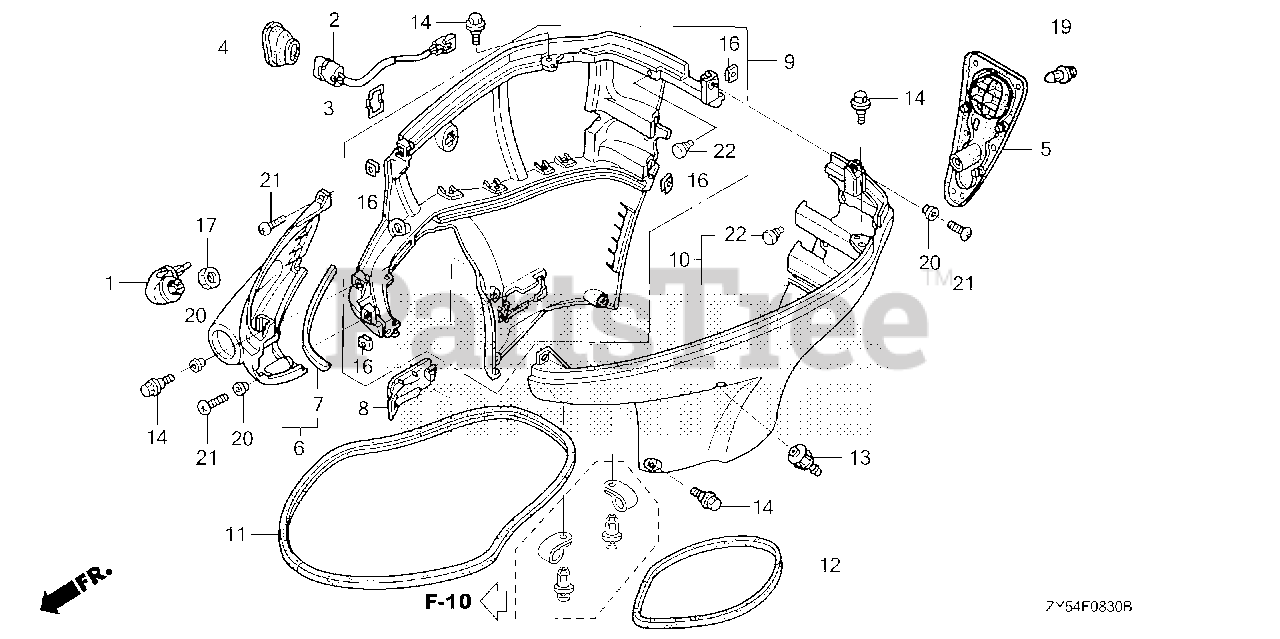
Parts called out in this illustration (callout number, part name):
1	CAP, WATER JOINT
2	SWITCH ASSY., POWER TILT
3	STAY, POWER TILT SWITCH
4	GROMMET, POWER TILT SWITCH
5	GROMMET, COVER (LOWER)
6	COVER, FR. SEPARATE *NH282MU* (OYSTER SILVER METALLIC-U)
7	SEAL, FR. SEPARATE COVER
8	COVER, DRAIN PLUG *NH282MU* (OYSTER SILVER METALLIC-U)
9	COVER, R. ENGINE (LOWER) *NH282MU* (OYSTER SILVER METALLIC-U)
10	COVER, L. ENGINE (LOWER) *NH282MU* (OYSTER SILVER METALLIC-U)
11	SEAL A, COVER (LOWER)
12	SEAL B, COVER (LOWER)
13	GROMMET, WATER CHECK
14	BOLT, SPECIAL (6X17)
17	NUT, HEX. (16MM)
19	CLIP, SPLASH GUARD
20	COLLAR, DISTANCE (6.5X9X11.5)
21	SCREW, PAN (6X25)
22	RUBBER B, STAND STOPPER
